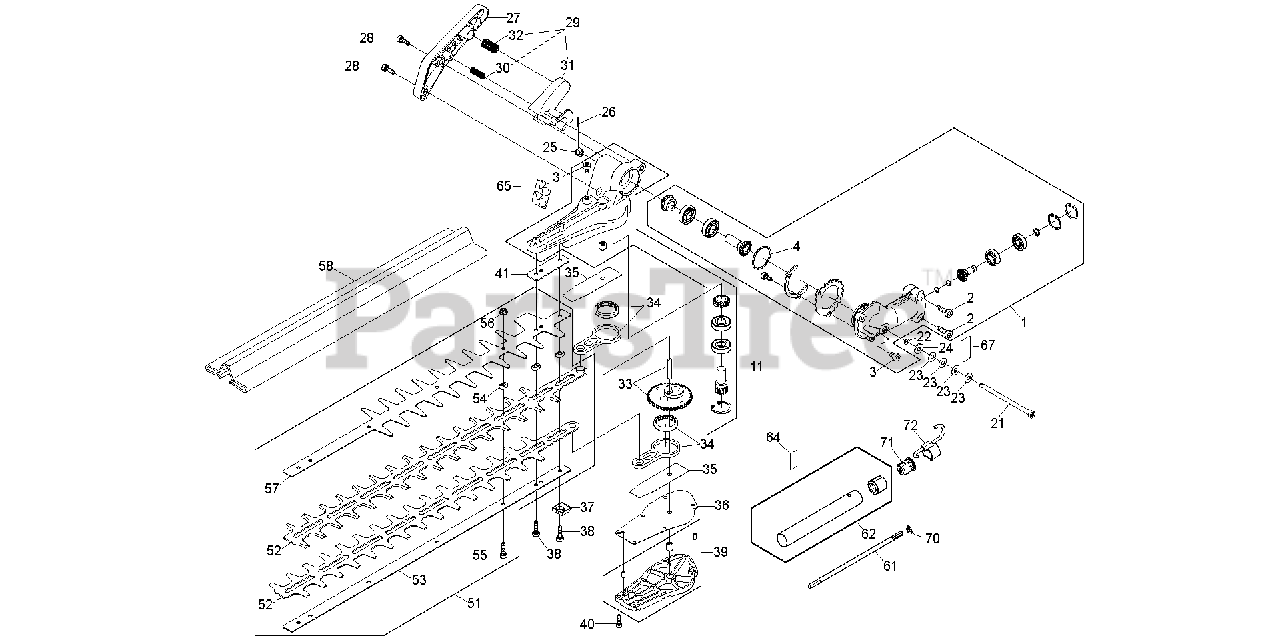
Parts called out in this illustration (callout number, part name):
1	HOUSING C, GEAR
2	BOLT, TORX (6X20)
3	BOLT, TORX (6X8)
4	O-RING (S-35)
21	BOLT, TORX (6X103)
22	O-RING (P-6)
23	SPRING, CONED DISK (DB-6H ACP)
25	NUT, CASTLE (M6)
28	BOLT, TORX (5X18)
32	SPRING, BIG
34	ROD, CONNECTING
35	PLATE, THRUST
38	BOLT, TORX (5X20)
39	COVER, GEARBOX
40	BOLT, TORX (4X16)
41	PLATE, CUTTER
51	CUTTER ASSY.
55	BOLT, TORX (5X15)
56	NUT, FLANGE LOCK (M5)
57	CUTTER GUIDE
58	COVER, CUTTER
61	SHAFT, DRIVE
64	MARK, ARROW
65	MARK, CAUTION
67	MARK, EMBLEM (SSHH)
